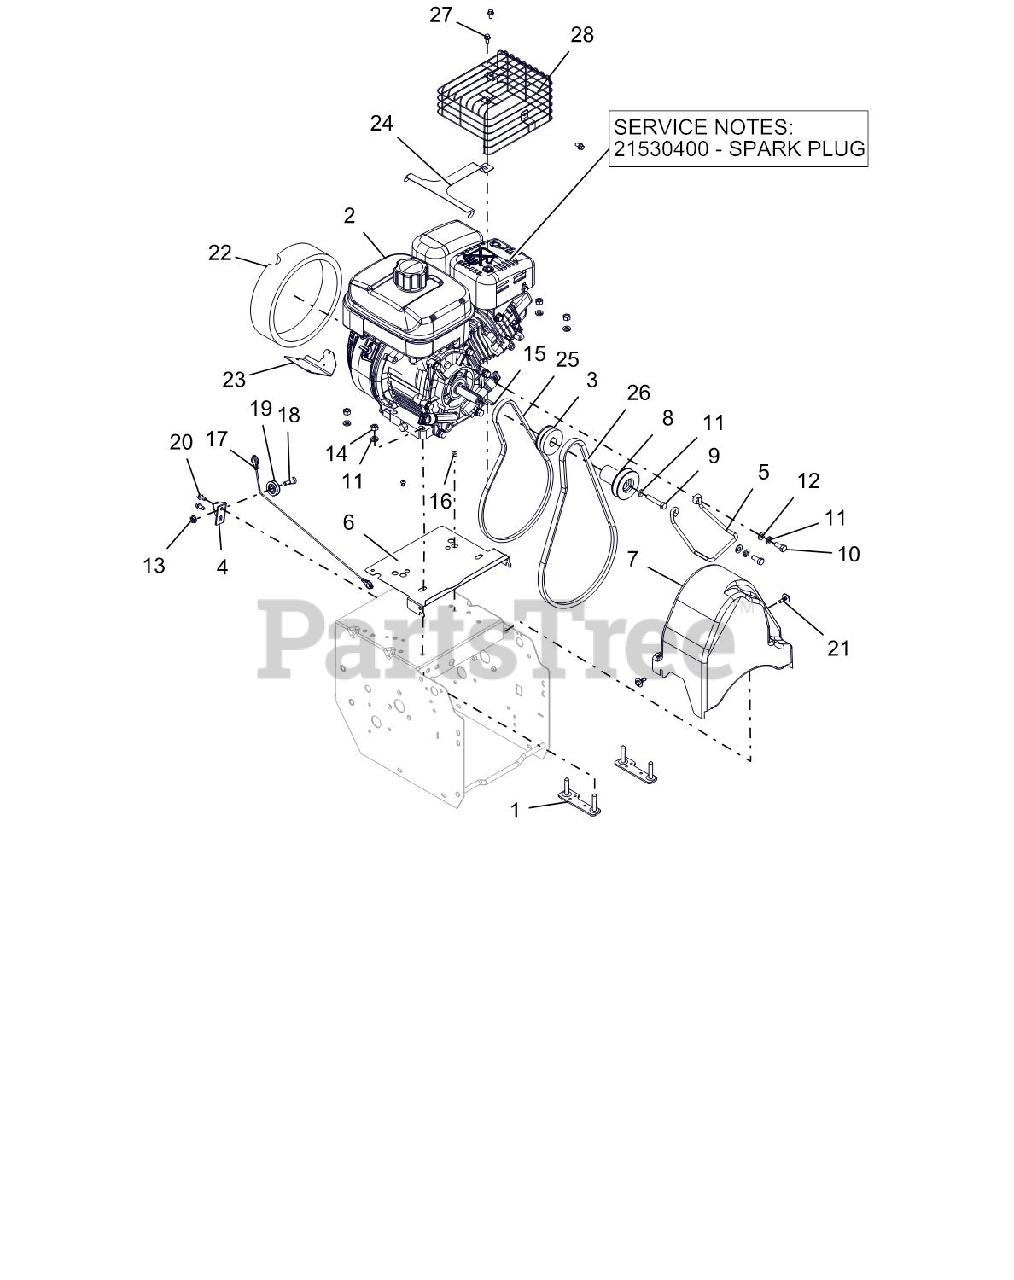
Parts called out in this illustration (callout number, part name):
1	STRAP, ENGINE BOLT-WELDMENT
2	PLUG, SPARK - TEC. SNO-THRO
2	SUBARU EX17 120V ALL-SEASON
3	PULLEY, TRACTION
4	BRACKET, CABLE PULLEY
5	BELT FINGER
6	BAFFLE, COMPACT
7	BELT COVER
8	SHEAVE, AUGER DRIVE
9	@BLT-HEX .31-24X1.75 GR5 YWZC
10	BLT-HEX .31-24X.75 YWZC GR5
11	WSHR-LK .312X.097 HVY YWZC
12	@WSHR-FL-STL.344X.688X.065YWZC
13	@NUT-LK-CTR-FLG .25-20 YWZC
14	@NUT-HEX .31-18 YWZC
15	KEY-SQ .188X.75X.188
16	RVT-POP .187 YZ
17	CABLE, LOWER TRACTION (CMPCT)
18	BOLT, SHLDR-.375X.375X.25-20
19	PULLEY, CABLE
20	SCR-TAP .25-20X.50 HWH TR YWZ
21	SCR-TAP .25-20X.5 CAPTIVE
22	FOAM COVER, RECOIL-SUBARU
23	BRACKET, SWITCH-SUBARU
24	GUARD, SNOW-SUBARU EX17
25	V-BELT, 3L-WRAPPED
26	V-BELT, HA-RAW EDGE
27	BLT-SERHFWH M6X1.0X12 8.8 CZ
28	GUARD,MUFFLER,SUB 20A-37303-11
